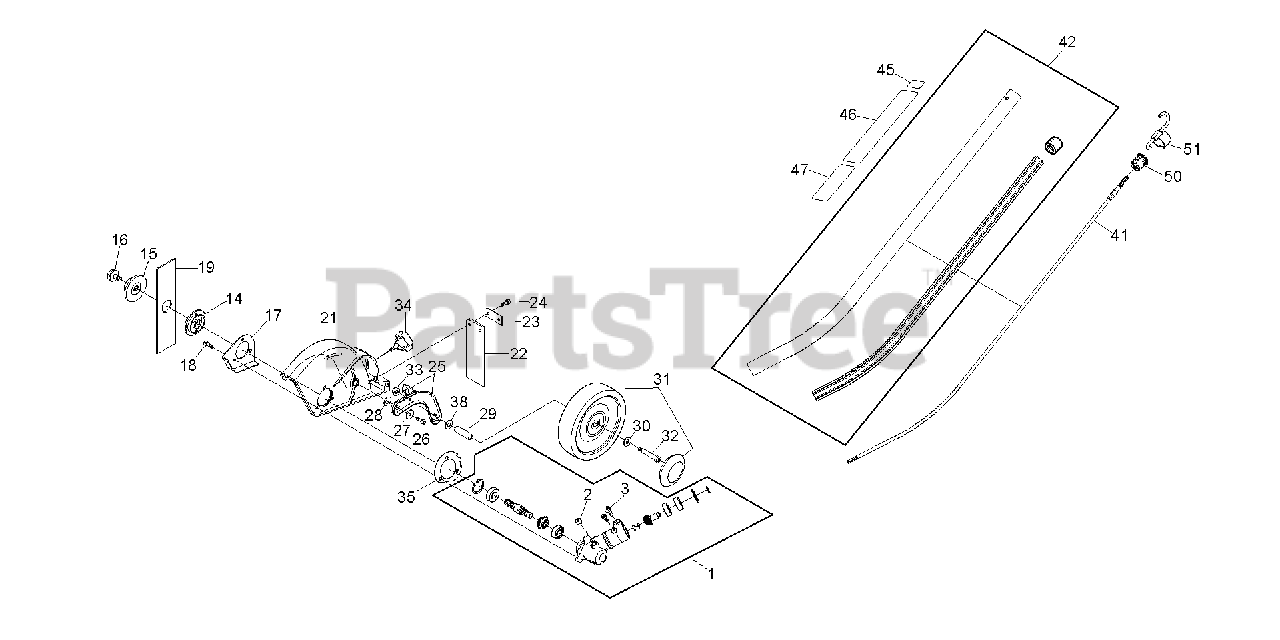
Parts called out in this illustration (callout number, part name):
1	CASE ASSY., GEAR B
2	BOLT, TORX (6X8)
3	BOLT, TORX (6X20)
14	HOLDER A, BLADE
15	HOLDER B, BLADE
16	BOLT-WASHER (8X18.5LH)
18	BOLT, TORX (5X15)
22	COVER, RUBBER
23	CATCH, RUBBER COVER
24	BOLT, TORX (5X15)
26	BOLT, TORX (5X15)
28	WASHER, SPECIAL
32	SCREW, SHOULDER
33	NUT, FLANGE (6MM)
41	SHAFT, FLEXIBLE
45	MARK, ARROW
46	MARK, CAUTION
47	MARK, EMBLEM (SSET)
